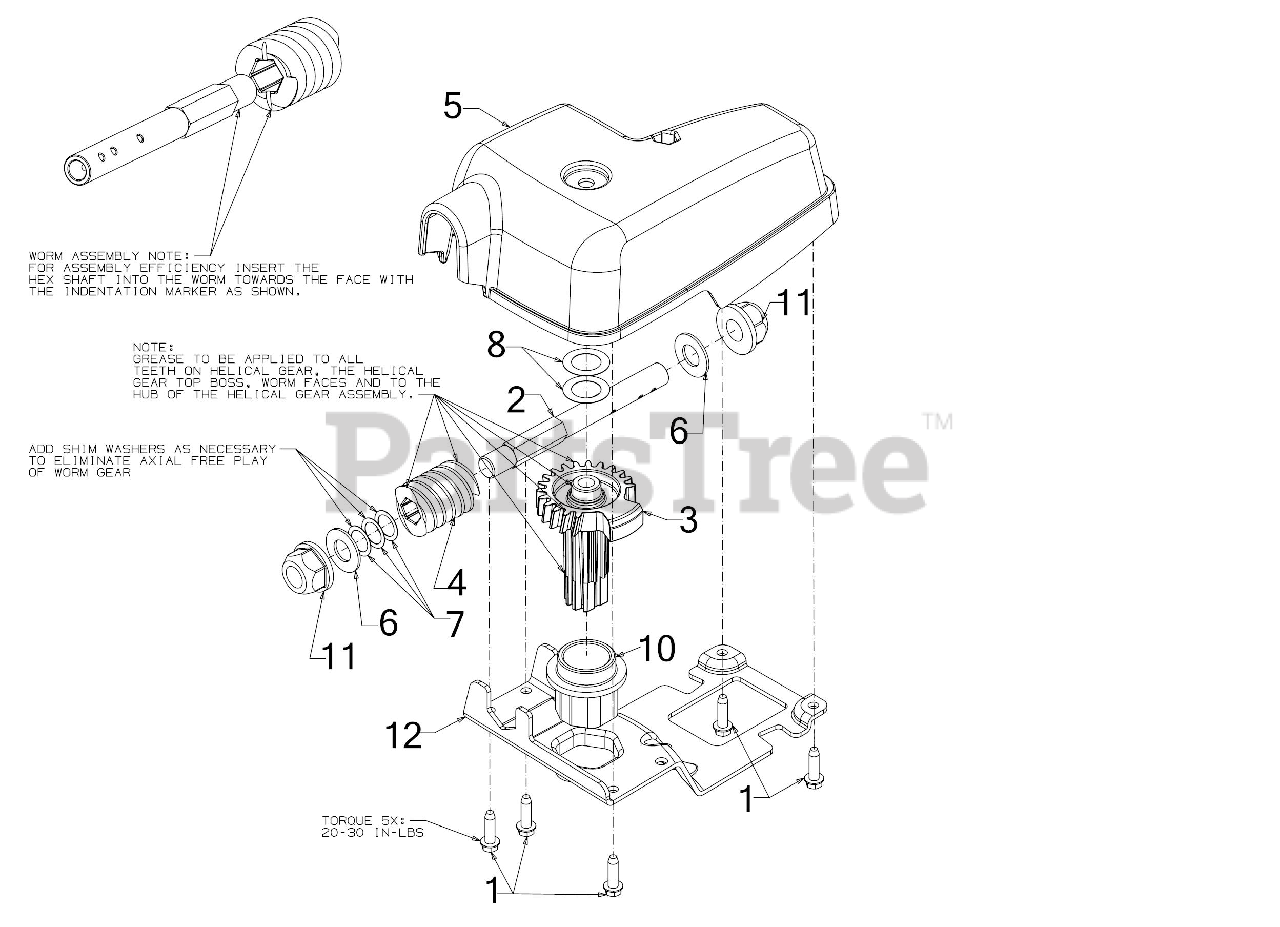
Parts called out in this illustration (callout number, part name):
1	SCREW #12-16 .75
3	HELICAL GEAR- 23
4	NYLON WORM
5	CHUTE GEARBOX COVER
6	FLAT WASHER .510 x 1.00 x .060
7	FLAT WASHER .504 X.700X.010
8	SHIM WASHER .632X1.000X.010:HD
10	HEX FLANGE BEARING
11	FLANGE BEARING
12	CHUTE ROTATION BRACKET
